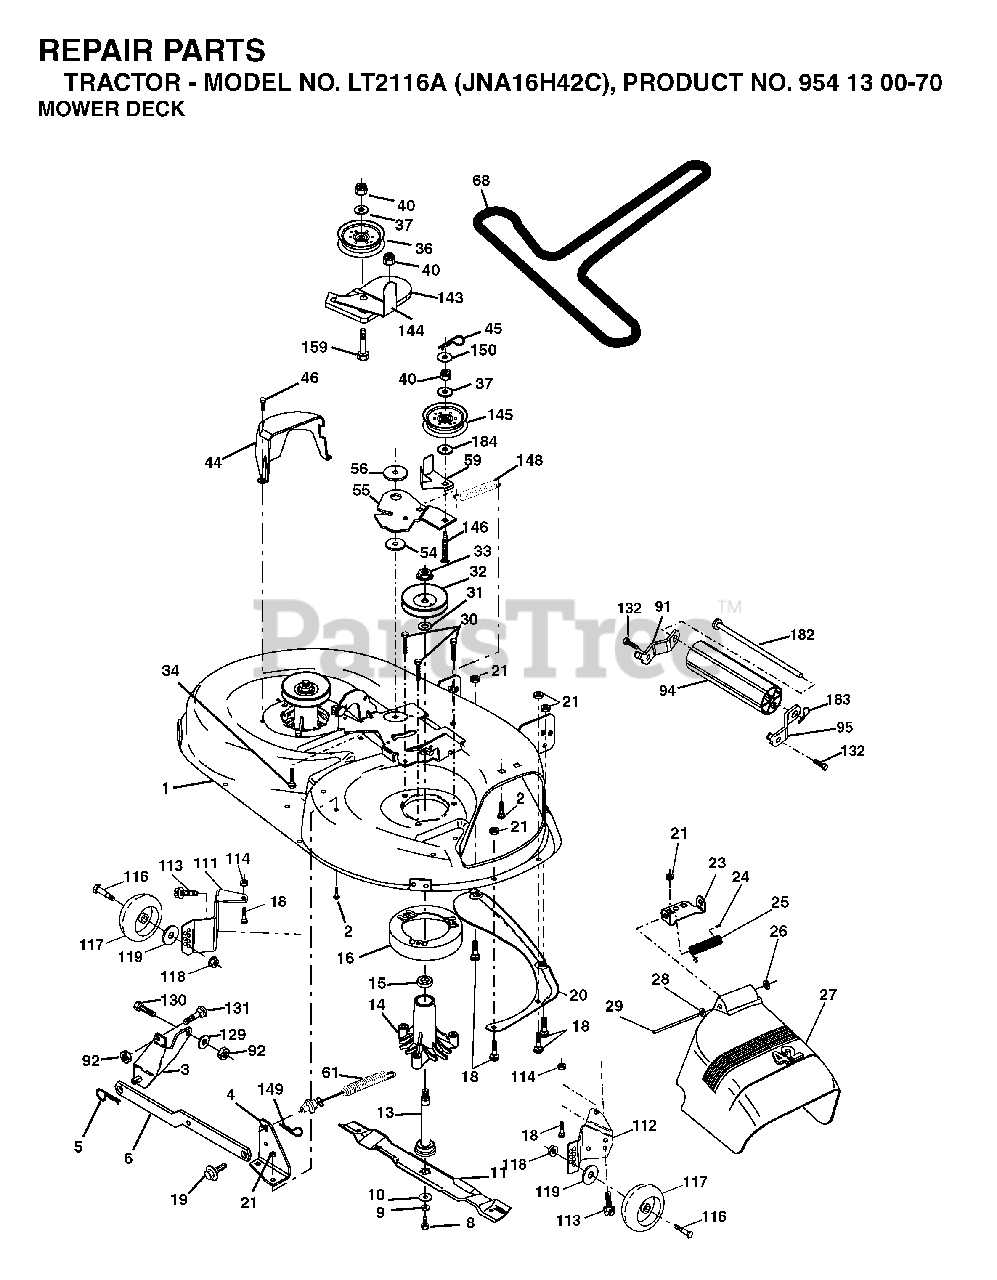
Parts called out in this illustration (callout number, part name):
1	42" DECK KIT
2	BOLT
3	BRKT ASM SWAY BAR
4	BRACKET SWAY BAR 42" DECK
5	RETAINER-SPRNG RB
6	BAR SWAY DECK
8	BLADE BOLT
9	LOCKWASHER
10	WASHER.BLADE
11	BLADE.42".MULCH
13	SHAFT ASM VENT
14	HSG MANDREL
16	STRIPPER, MWR ROUND
18	BOLT
19	BOLT SHD 5/16-18
20	BAFFLE.VORTEX
21	LOCKNUT
23	BRKT, DEFL. MOWER
24	CAP-SLEEVE LT
25	SPRING TORSION
26	NUT PUSH M
27	SHIELD DEFLECTOR
28	WASHER
29	ROD.HINGE
30	SCREW, WASHER HEAD
31	WASHER
32	PULLEY/MANDREL
33	NUT, FLG TOPLOCK 9/16"
34	BOLT
36	FLAT IDLER PULLEY
40	LOCKNUT
44	GUARD MANDREL LH BLACK
45	RETAINER M
46	SCREW.1/4-20X5/8
55	ARM IDLER 42" MOWER LT/YT
56	SPACER.RETAINER.MOWER
59	GUARD, BELT
61	SPRING EXT ELEC CLUTCH
68	V-BELT PRIMARY 42"
91	BRACKET ASM NOSEROLLER LH
92	NUT
94	NOSE ROLLER
95	BRACKET ASM NOSEROLLER RH
111	BRACKET, WHEEL
112	BRACKET, WHEEL
113	SCREW.3/8-16X.625
114	NUT
115	BOLT
116	PEDAL COVER T
117	WHEEL.GAUGE.STANDARD
118	LOCKNUT
119	WASHER
129	WASHER
130	BOLT
131	BOLT D
132	SCREW 3/8-16X3/4
143	BRACKET, ARM IDLER
144	KEEPER.BELT.42".CLUTCH.CABLE
145	PULLEY
146	BOLT, CARRIAGE IDLER BLACK
148	IDLER RETURN SPRING
149	SPRING.RETAINER.YELLOW.ZINC
150	WASHER PM
159	BOLT
182	ROD ROLLER NOSE STANDARD
183	SPRING RETAINER
184	WASHER
